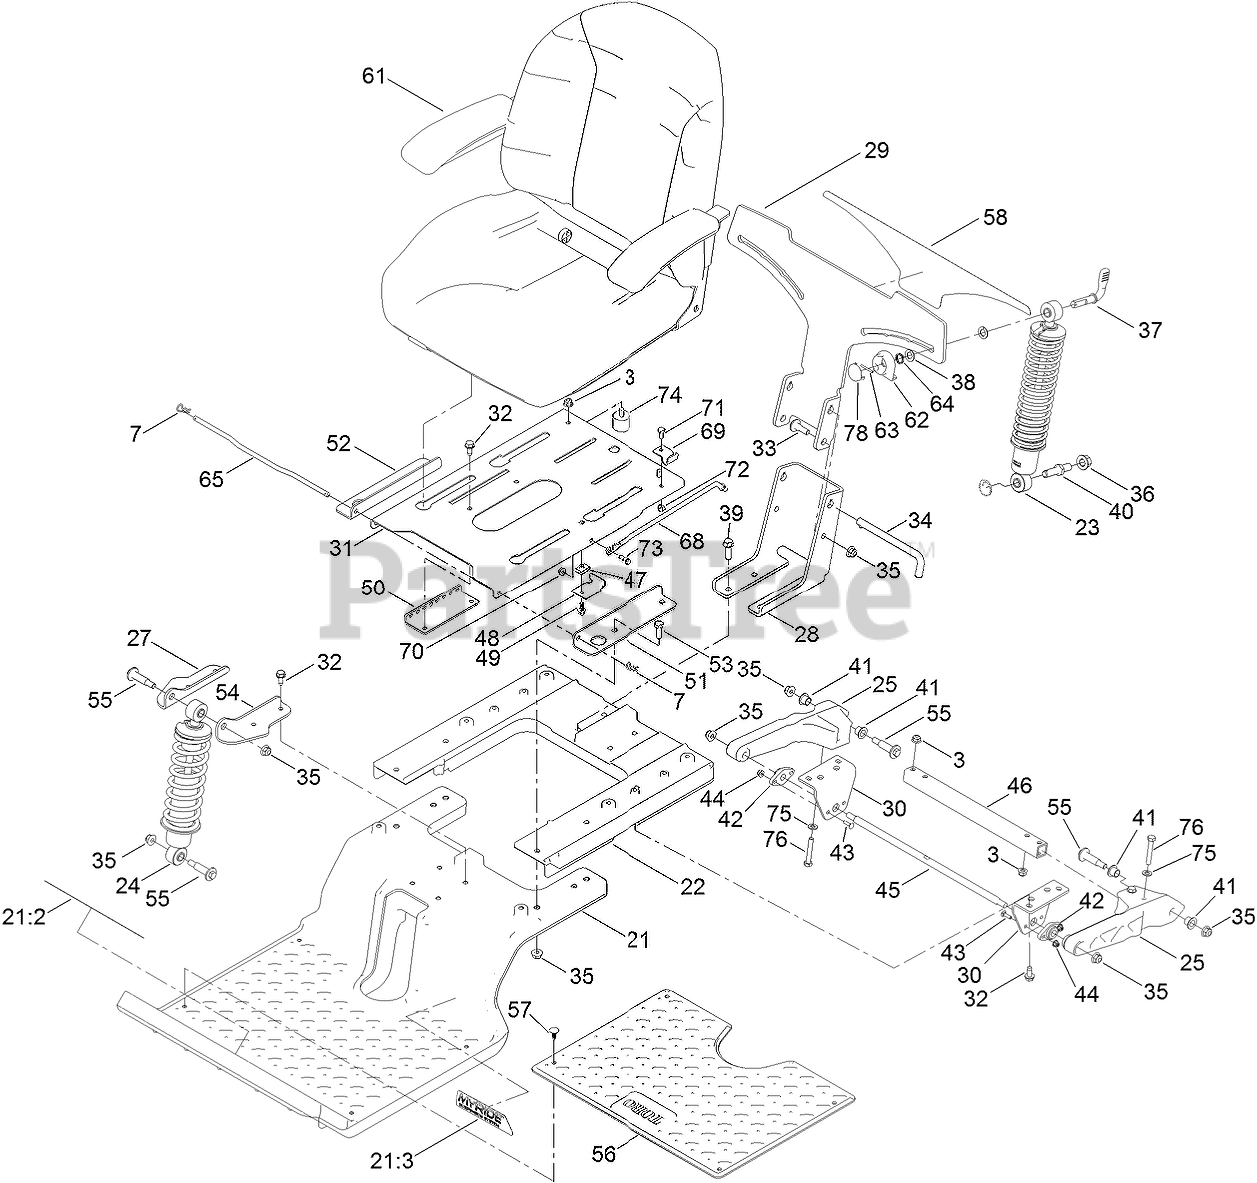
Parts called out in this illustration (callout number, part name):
3	NUT-HF, NI
7	PIN-COTTER
21	SUBFRAME-FRONT
21:2	DECAL-DANGER
22	SUBFRAME-REAR
23	SHOCK/SPRING ASM
24	SHOCK ASM
25	TRAILING ARM
27	BRACKET-SHOCK MOUNT, UPPER (RH)
28	BRACKET-MOUNT, LOWER
29	PLATE-MOUNTING, SHOCK
30	BRACKET-MOUNT, SWING ARM
31	PAN-SEAT
32	SCREW-HWHTF
33	SCREW-SHOULDER, HHF
34	PIN-HOC
35	NUT-HF, NI
36	NUT-LOCK
37	HANDLE-ADJUSTMENT
38	WASHER-THRUST
39	SCREW-THD
40	BOLT-SHOULDER
41	BUSHING-FLANGE
42	BEARING-FLANGE
43	SCREW-CARR
44	NUT-HF
45	ROD-PIVOT
46	TUBE-ARM, TRAILING
48	BRACKET-STOP, SEAT
49	SCREW-HHF
50	BRACKET-LATCH, SEAT
51	BRACKET-SEAT, RH
52	BRACKET-SEAT, LH
53	SCREW-HH
54	BRACKET-SHOCK MOUNT, UPPER (LH)
55	BOLT-SHOULDER
56	FLOORMAT
57	PLUG-PLASTIC
58	DECAL-ADJUSTMENT
61	SEAT ASM
62	LOCK-CAM
63	PIN-LOCK, CAM
64	SPRING-WAVE
65	ROD-STOP
68	BRACE-SEAT
69	BRACKET-BRACE, SEAT
70	NUT-HF
71	SCREW-HH
72	NUT-LOCK, NI
73	BOLT-SHOULDER
74	BUMPER-RUBBER
75	WASHER-PLAIN
76	SCREW-HH
78	CAP-LOCK, CAM
